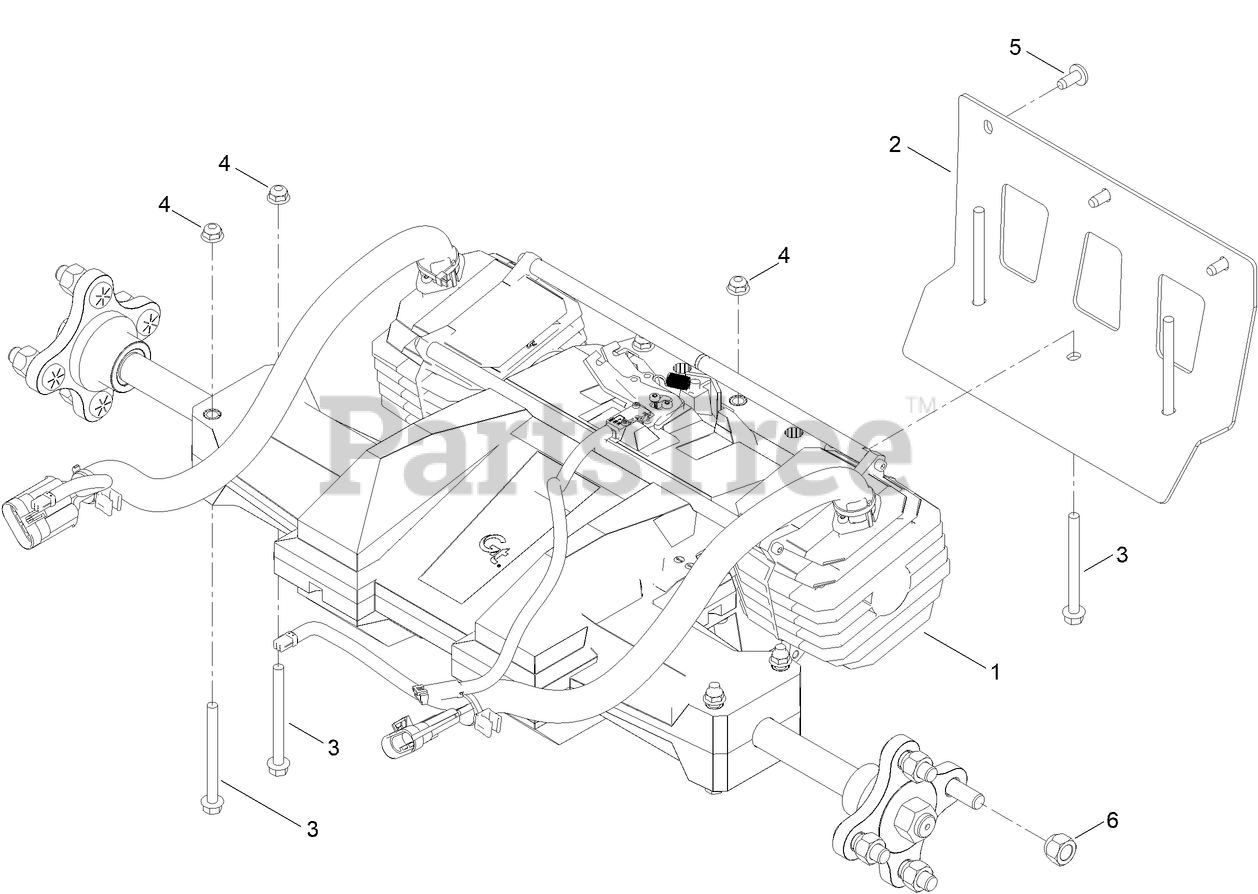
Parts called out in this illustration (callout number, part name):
1	TRANSAXLE-ELECTRIC, 20"
2	BRACKET-TRANSMISSION
3	SCREW-HH
4	NUT-HF
6	NUT-LUG
